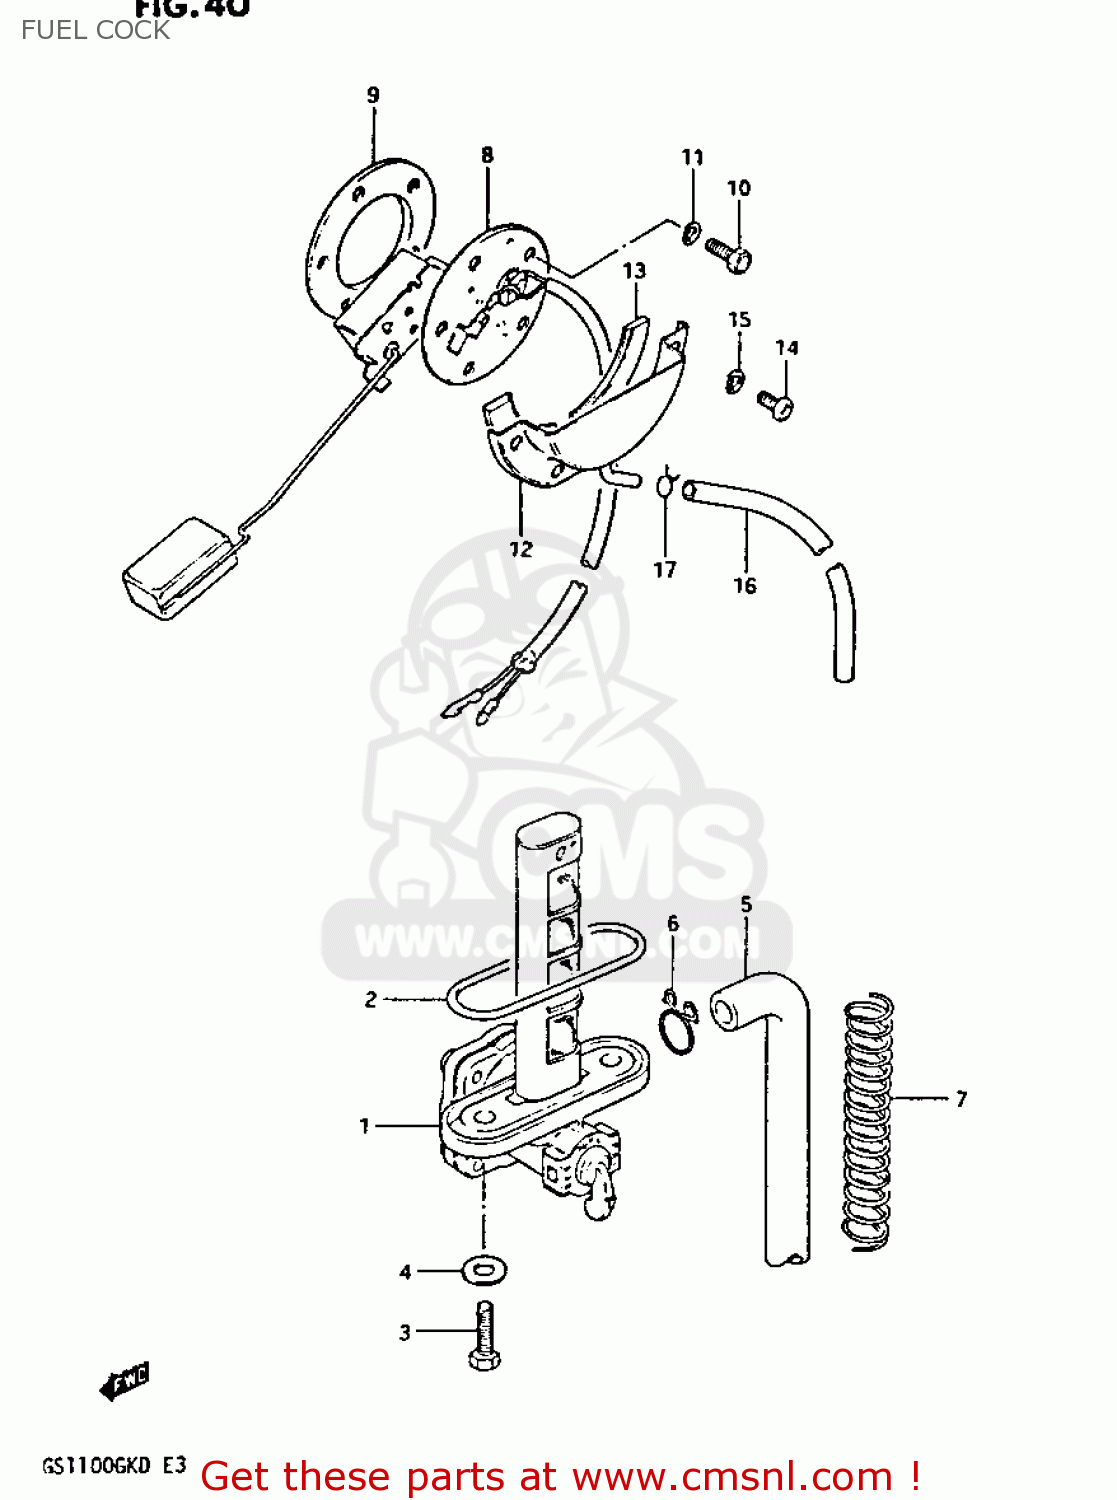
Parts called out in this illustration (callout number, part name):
1	COCK ASSY,FUEL
2	O RING
3	BOLT(6X20)
4	GASKET(5.8X13X1.2) (NAS)
5	HOSE(7X10.2X2000)
6	CLIP
7	SPRING
8	GAUGE ASSEMBLY,FUEL LEVEL
9	GASKET,FUEL LEVEL GAUGE (NAS)
10	BOLT 5X10
11	LOCK WASHER
12	PLATE,FUEL DRAIN
13	GASKET (NAS)
14	SCREW
15	LOCK WASHER
16	HOSE
17	CLIP
